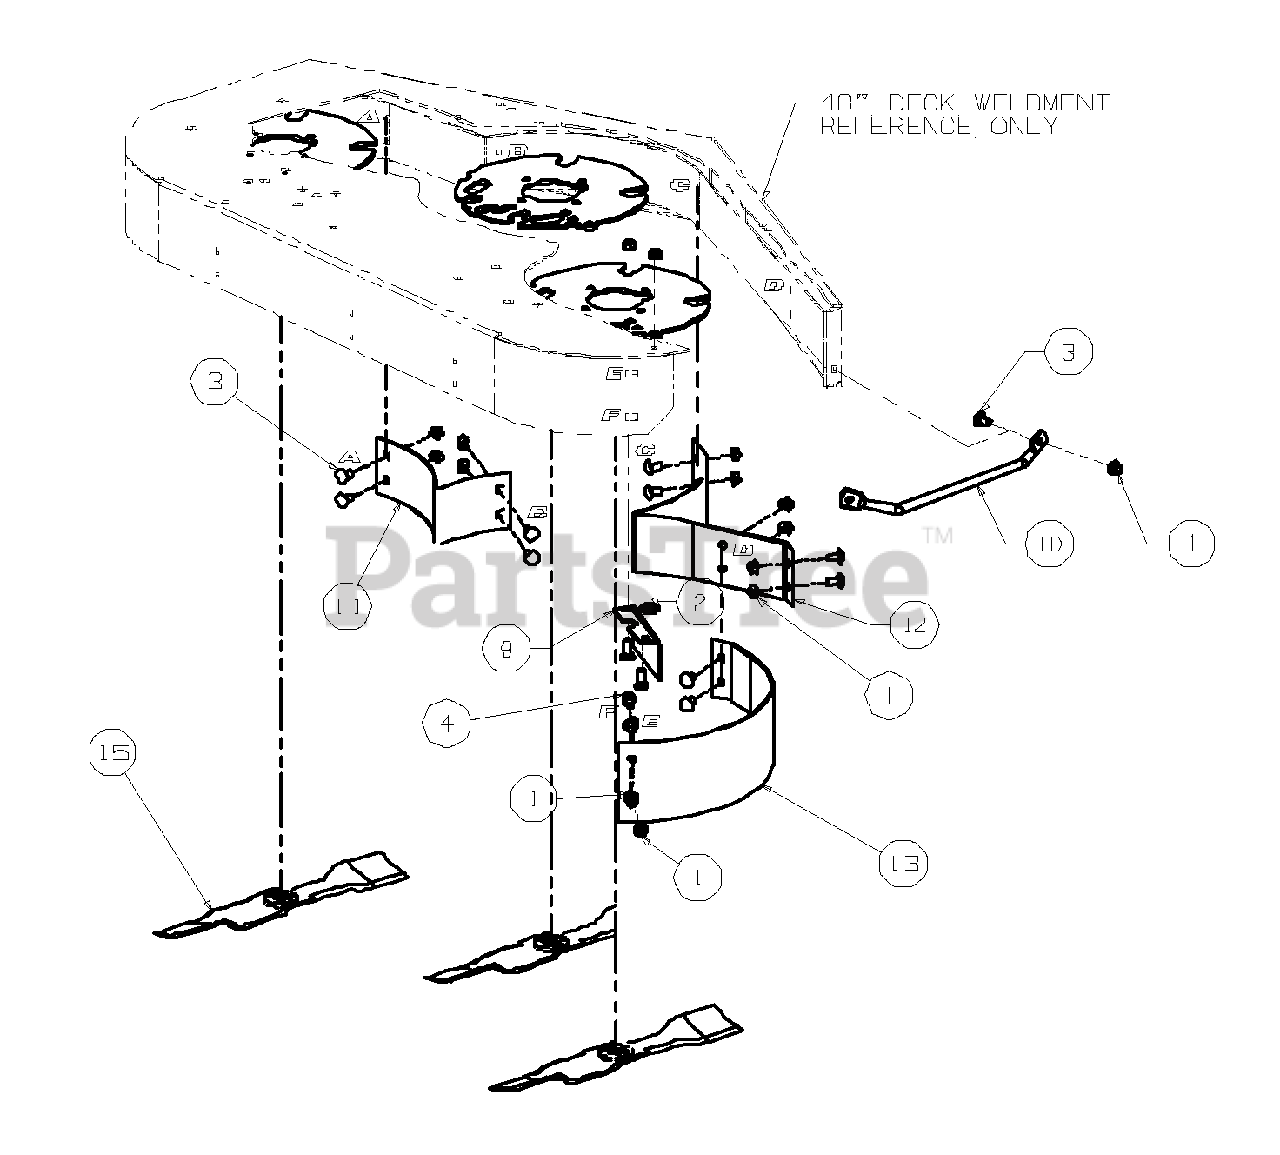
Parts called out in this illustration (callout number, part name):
1	NUT:HEX 3/8-16 FLG LOCK
2	WASHER:IDLER
3	BOLT:CARR 3/8-16 X .75 LG
4	BOLT:CARR 3/8-16 X 1.0 LG
9	BRKT:CHUTE:FAB DECK
10	GUARD:FINGER:FAB DECK
11	BFL:MULCH:FAB 48 LH
12	BFL:MULCH:FAB 48 CENTER
13	BFL:MULCH:FAB 48 RH
15	BLADE:17.0:MULCH:0.756 ID
